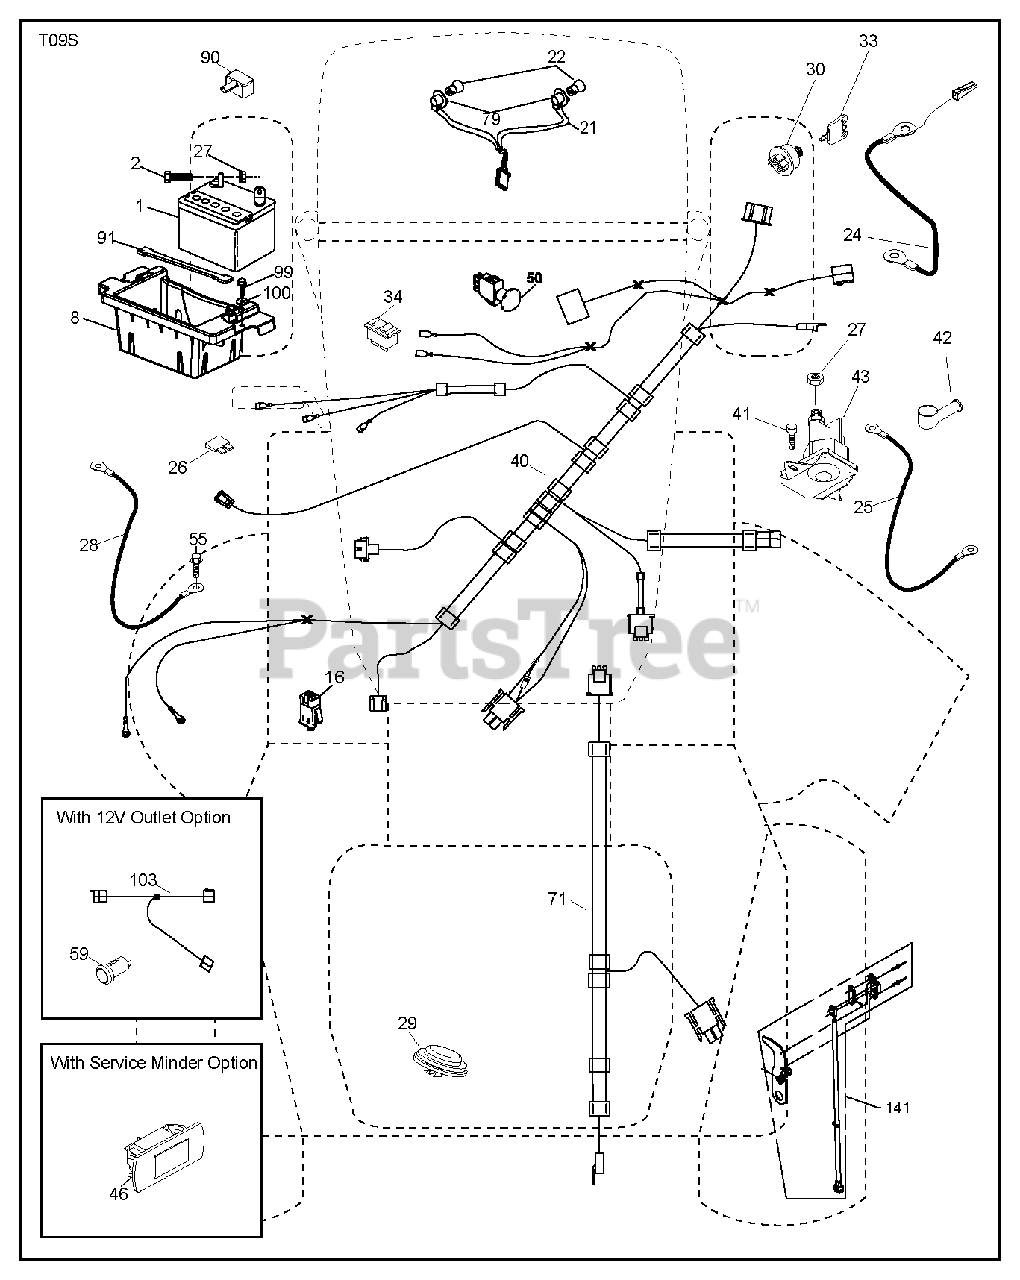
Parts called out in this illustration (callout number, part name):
1	REPL BY 532 12 38-99
8	BOX.BATTERY.MOUNT.FRONT.LT
16	SWITCH INTERLOOK PUSH-IN
21	HARNESS.LIGHT W/4152J BULBS
24	CABLE.BATT.POS.WIRE.TG.DA SOL
25	CABLE.STARTER.6G.BL/RED.17.5
27	NUT
28	CABLE GROUND 6 GA 21" 90T BLK
29	SWITCH.SEAT.DELTA.OPC.
30	SWITCH.IGN.DELTA.W.LGH.ROS
33	KEY/CHAIN.BLISTER.PACK*SUBS/2*
40	HARNESS.IGN.DASH.HUQ/P
41	SCREW
42	TERMINAL COVER
43	SOLENOID.W/BRASS.PLUNG
46	GUAGE.SRVCMNDR.HRMTR.
50	PTO SWITCH
55	SCREW 5/16"
71	HARNESS-CHASSIS SUB
79	BULB HOLDER ASM.
90	COVER.TERMINAL.BATTERY
91	STRAP, BATTERY MOUNT
99	SCREW HEXWSHR 1/4-20X3/4
141	KIT.G700/G730.ROS.SERV(71750)
